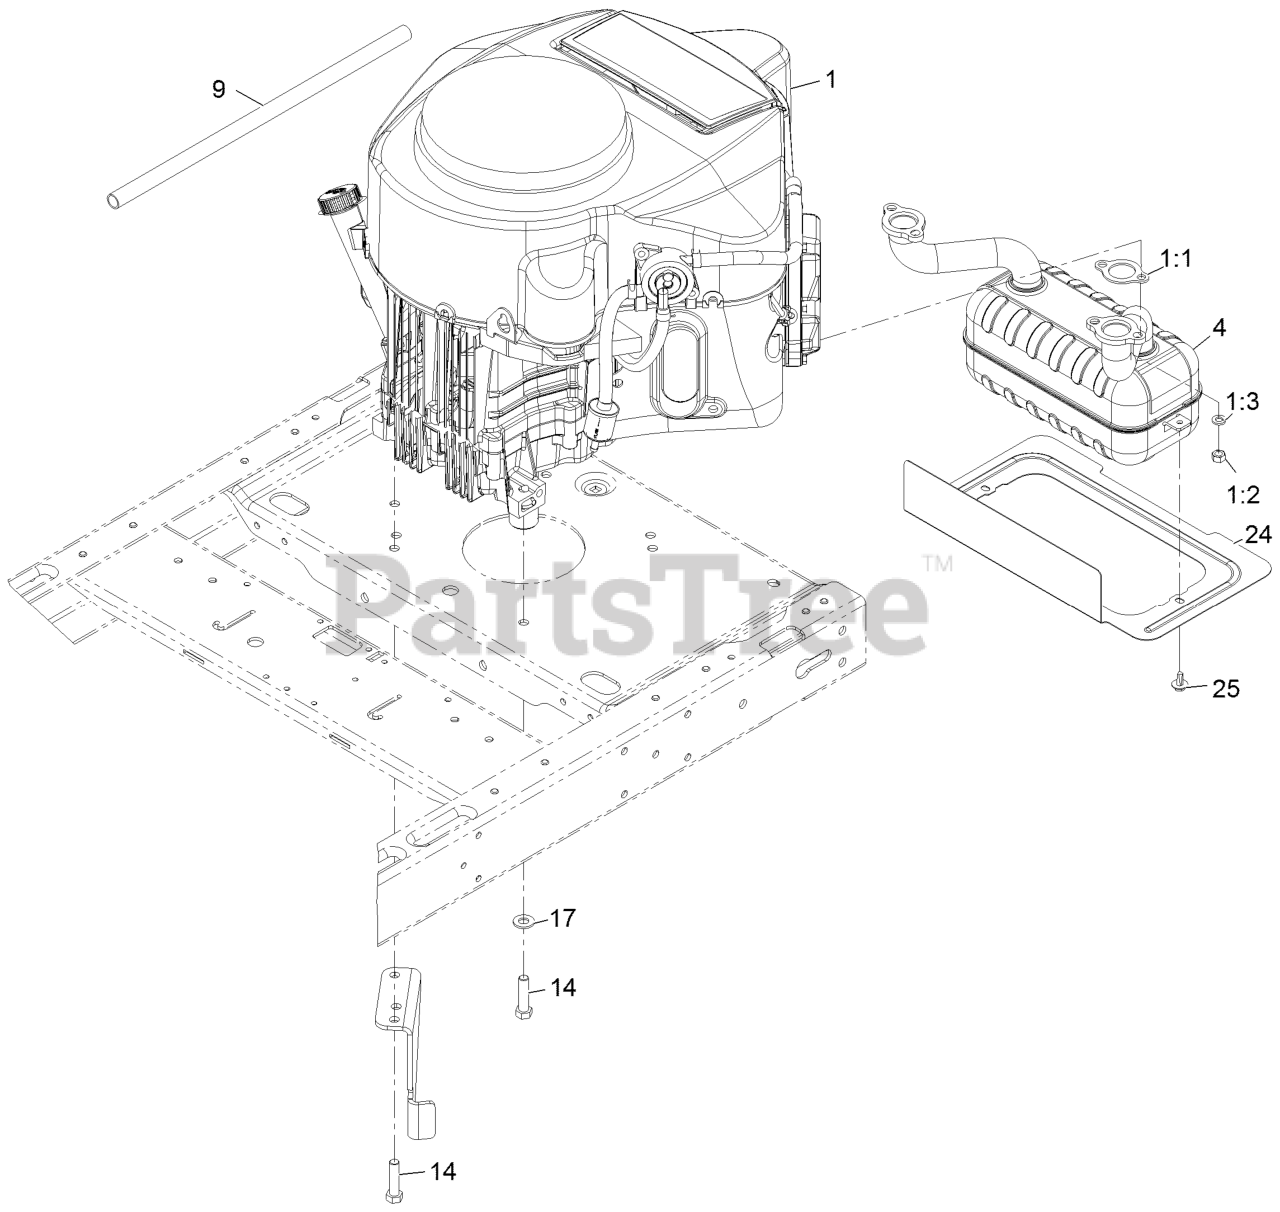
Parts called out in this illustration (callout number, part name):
1	Engine-Kawasaki
1:1	GASKET-EXHAUST
1:3	WASHER-LOCK
4	MUFFLER-KAWASAKI
9	TUBE-DRAIN, OIL
14	BOLT-HH
17	WASHER-FLAT
24	SHIELD-HEAT
25	SCREW-HHFTF
